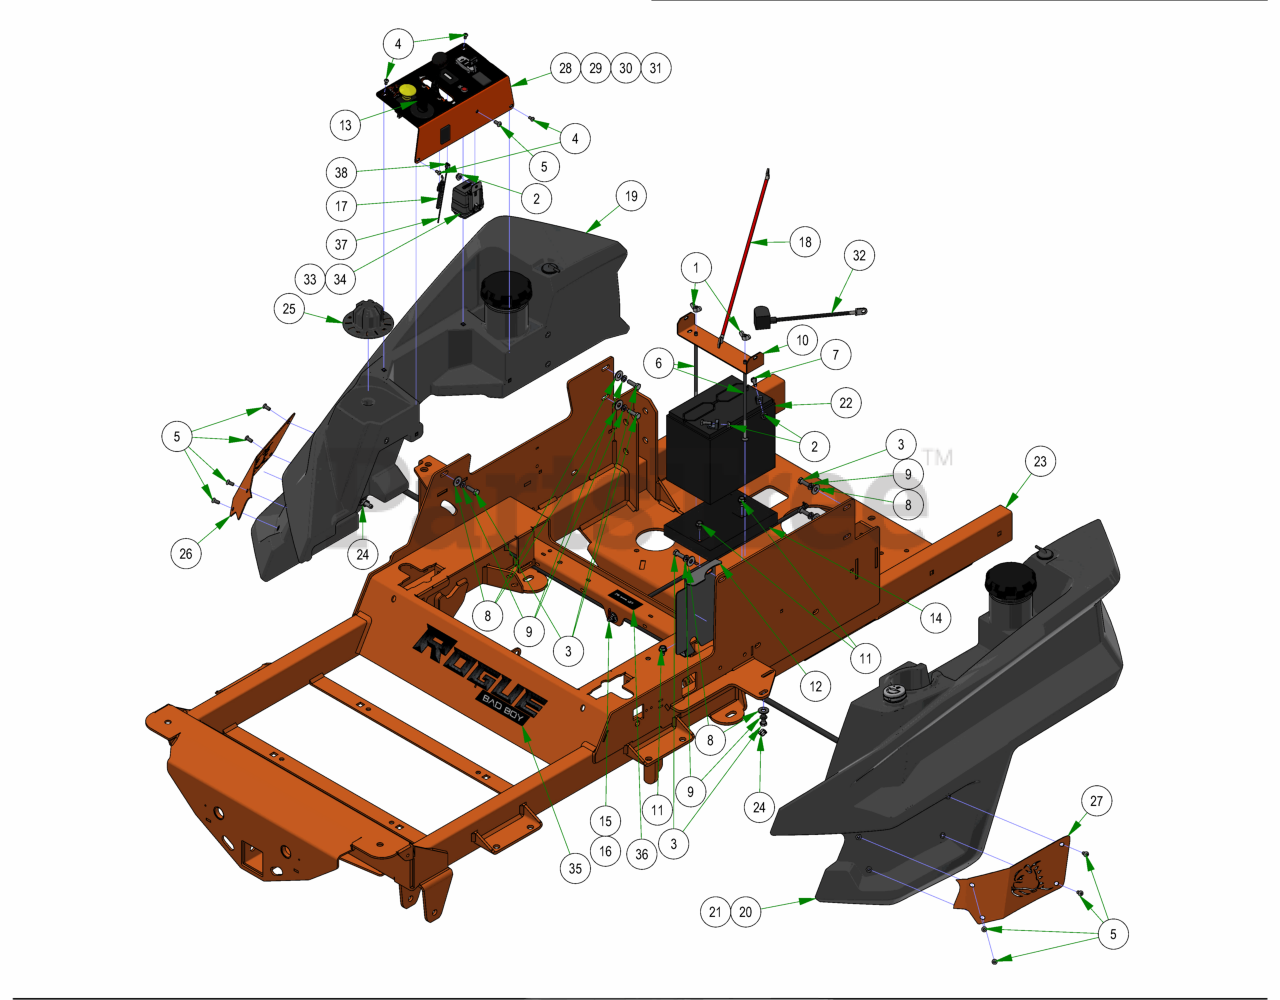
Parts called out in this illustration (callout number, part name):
1	1/4-20 WING NUT FORGED (TYPE A) LIGHT SERIES ZINC
2	1/4-20 HEX SERRATED FLANGE NUT HARD/ZINC
3	5/16-18 X 1 HEX CAP SCREW (GR.5) ZINC
4	10-32 X 3/8 BUTTON SOCKET CAP SCREW 18-8 STAINLESS STEEL
5	1/4-20 X 1/2 BUTTON SOCKET CAP SCREW 18-8 STAINLESS STEEL
6	1/4-20 X 8 CARRIAGE BOLT (MIN 6" THREAD) ZINC
7	1/4-20 X 3/4 HEX CAP SCREW (GR.5) ZINC
8	5/16 USS FLAT WASHER (7/8 OD) ZINC
9	5/16 SPLIT LOCKWASHER ZINC
10	2023 Rogue Battery Hold Down Plate
11	5/16-18 X 1/2 HWH unslot (F) tcs zinc
12	Rogue Fuel Gauge wire Bracket-Orange
13	Ignition Key
14	Battery Tray
15	2023 R-Series Fuel Line for Kohler
16	2023 Rebel Rogue Renegade Fuel Line for Kawasaki
17	Outlaw Throttle Cable
18	24" Red Battery Cable
19	2019 Right Rebel, Rogue, Renagade Fuel Tank (GAS)
20	2019 Left Rebel, Rogue, Renegade Fuel Tank (GAS)
21	2025 Left Rogue Fuel Tank w/Electronic Fuel Gauge
22	SP-35 Battery
23	2023 Rogue Frame - Painted
24	2 EAR CLAMP 12.5mm-15mm
25	2019 Deck Height Dial
26	2019 Outlaw Fuel Tank Insert - Right
27	2019 Outlaw Fuel Tank Insert - Left
28	Rebel/Rogue EFI Control Panel Assy
29	Rebel/Rogue Control Panel Assy
30	Rebel/Rogue Control Panel Assy-Drive by Wire
31	Rogue Control Panel Assy-Digital Display
32	Starter Cable
33	2025 Wiring Harness-Rogue Digital Display
34	2019 Wiring Harness-Rebel/Rogue
35	Rogue back Plate & Front Decal
36	R-Series Shut Off Valve Decal
37	16 AWG Black Insulated Wire for Tachometer
38	1/4" Female Quick Connect Terminal
